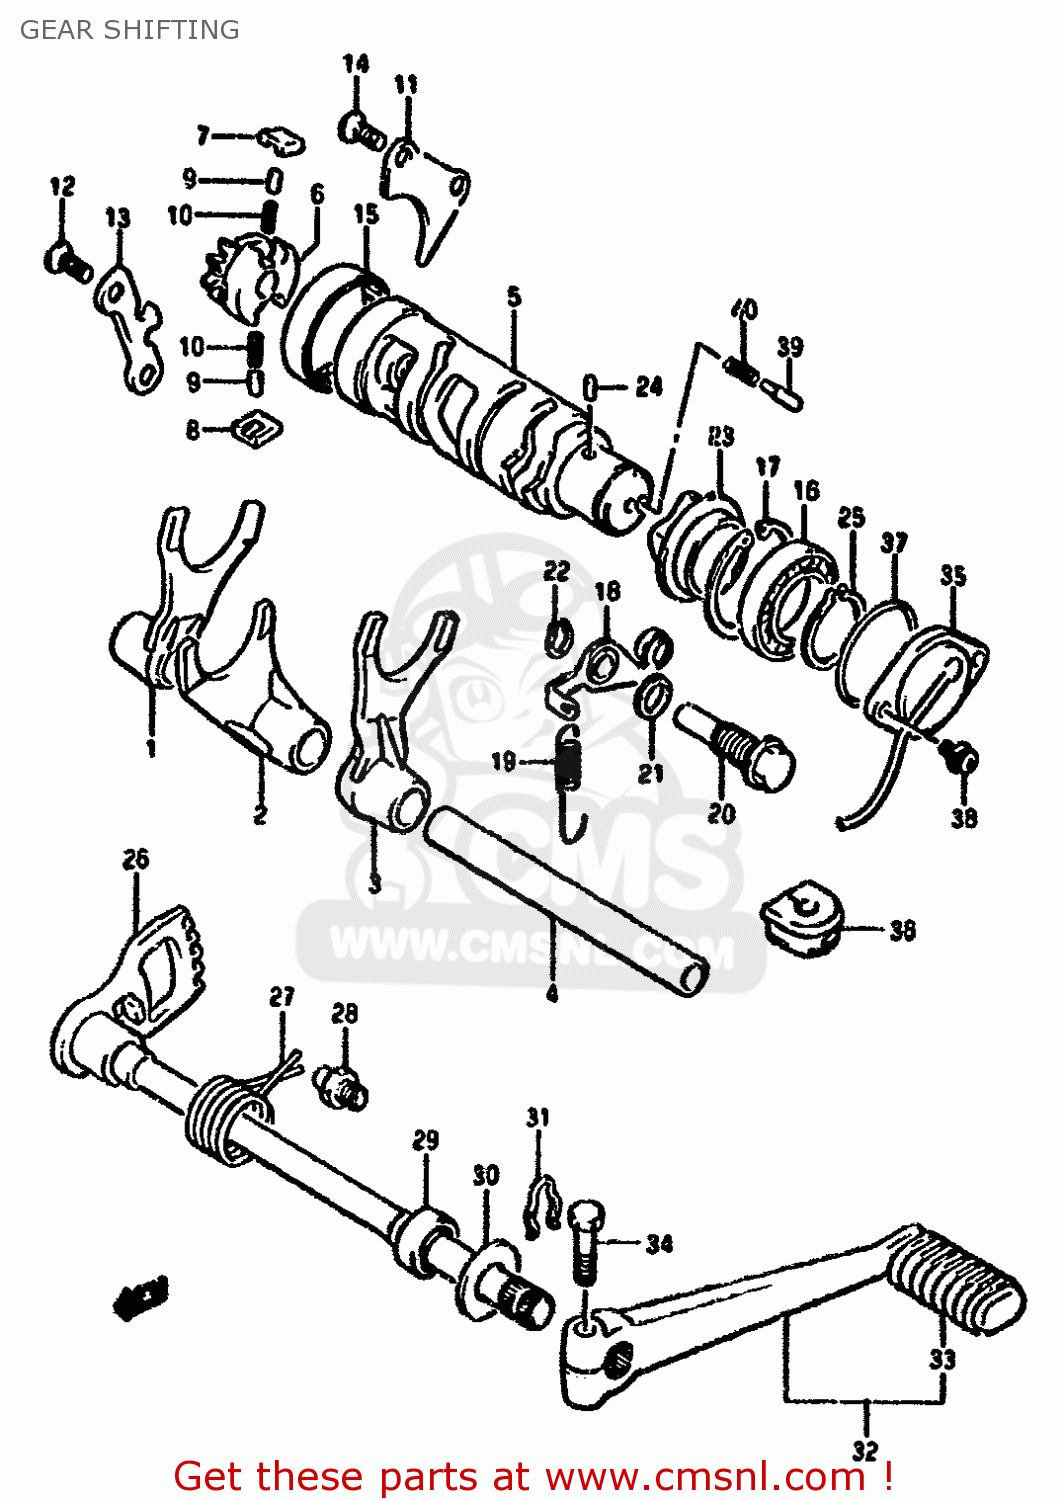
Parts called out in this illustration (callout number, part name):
1	FORK,GEAR SHIFT NO.1
2	FORK,GEAR SHIFT NO.2
3	FORK,GEAR SHIFT NO.3
4	SHAFT,GEAR SHIFT FORK(L:128)
5	CAM,GEAR SHIFT
6	GEAR,GEARSHIFT CAM DRIVE
7	PAWL,GEAR SHIFT NO.1
8	PAWL,GEAR SHIFT NO.2
9	PIN(5X8)
10	SPRING
11	LIFTER,GEAR SHIFT PAWL
12	SCREW
13	GUIDE,GEAR SHIFT CAM
14	SCREW
15	BEARING(43X49X12)
16	BALL BEARING
17	CIRCLIP
18	STOPPER,GEAR SHIFT CAM
19	SPRING
20	SHAFT,GEAR SHIFT CAM STOPPER
21	GASKET(10X14X3.6) (NAS)
22	CIRCLIP
23	PLATE,STOPPER
24	PIN 4X6
25	CIRCLIP
26	SHAFT,GEAR SHIFT
27	SPRING
28	STOPPER,GEAR SHIFT CAM
29	OIL SEAL
30	WASHER (12.5X27X1.6)
31	CIRCLIP,12 MM
32	LEVER ASSY,GEAR SHIFT
33	RUBBER,PEDAL
34	BOLT
35	TERMINAL BASE ASSY,NEUTRAL
36	GROMMET,LEADWIRE
37	O RING(D:2.4,ID:36.5)
38	SCREW
39	PIN(5X15.5)
40	SPRING
